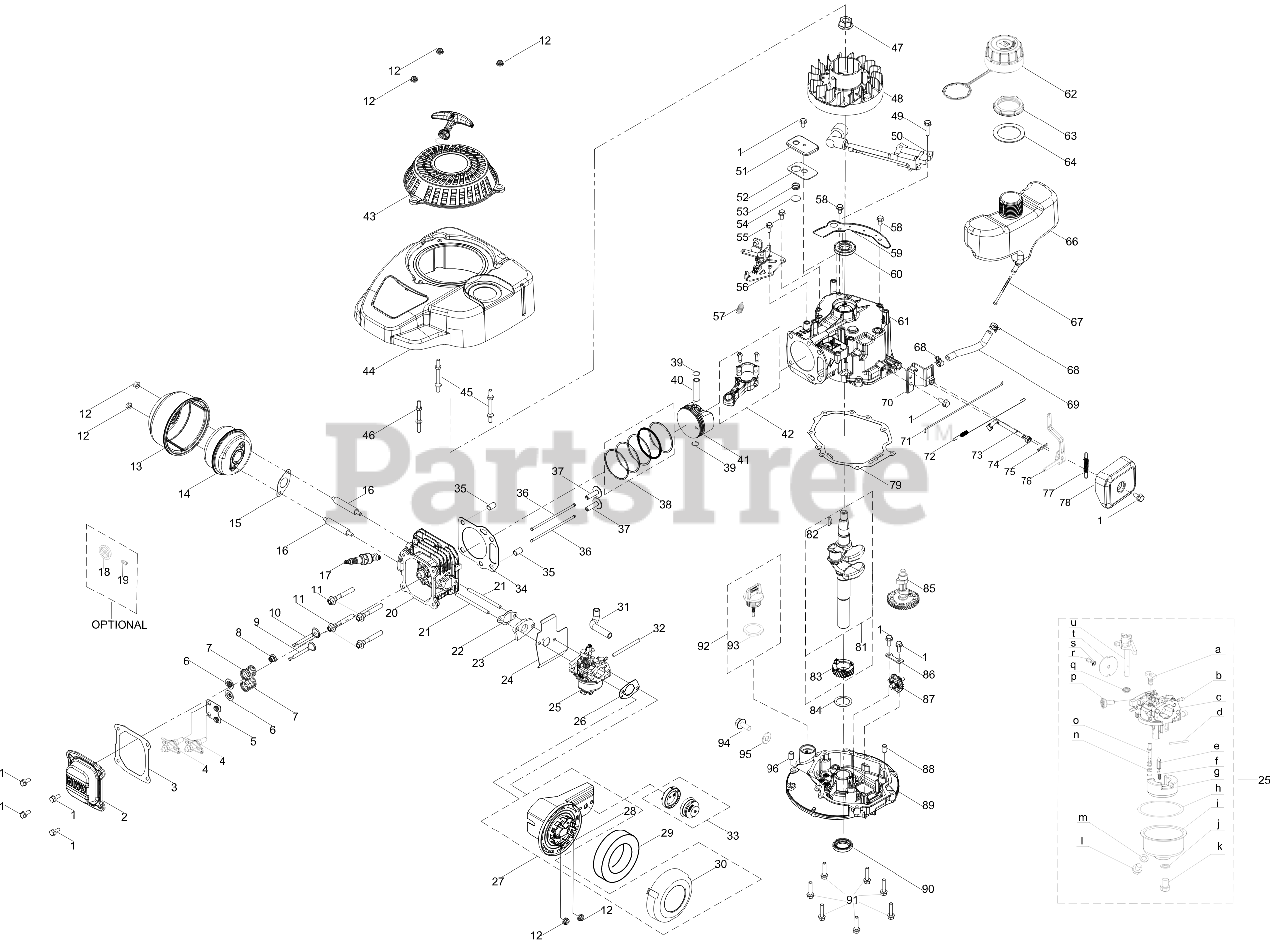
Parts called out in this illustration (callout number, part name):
1	BOLT M6-1 x 14 GR8.8
2	VALVE COVER
3	VALVE COVER GASKET
4	ROCKER ARM ASSEMBLY
5	PUSH ROD GUIDE
6	VALVE SPRING RETAINER
7	VALVE SPRING
8	INTAKE VALVE SEAL
9	EXHAUST VALVE
10	INTAKE VALVE
11	SCREW M8 x 54 GR10
12	HEX NUT
13	MUFFLER SHIELD
14	MUFFLER ASSEMBLY
15	MUFFLER GASKET
16	STUD M6-1 x 76
17	SPARK PLUG
18	SPARK ARRESTOR
19	SCREW M3.5 x 9.5
20	CYLINDER HEAD
21	STUD M6 x 98
22	CARBURETOR INSULATOR GASKET
23	CARBURETOR INSULATOR
24	CARBURETOR GASKET
25	CARBURETOR
26	AIR FILTER BASE GASKET
27	AIR FILTER ASSEMBLY
28	AIR FILTER BASE
29	FOAM AIR FILTER
29	Genuine Factory Parts AIR FILTER
30	AIR FILTER COVER
31	BREATHER HOSE
32	PRIMER HOSE
33	VENTED PRIMER ASSEMBLY
34	CYLINDER HEAD GASKET
35	DOWEL PIN
36	PUSH ROD
37	TAPPET (LIFTER)
38	PISTON RING SET
39	SNAP RING-PISTON PIN
40	PISTON PIN
41	PISTON
42	CONNECTING ROD ASSEMBLY
43	STARTER RECOIL ASSEMBLY
44	ENGINE SHROUD ASSEMBLY
45	STUD M6 x 75
46	STUD M6 x 73
47	FLYWHEEL NUT
48	FLYWHEEL
49	BOLT M6-1 x 25 GR8.8
50	IGNITION COIL ASSEMBLY
51	BREATHER COVER PLATE
52	BREATHER COVER GASKET
53	BREATHER VALVE SPRING
54	BREATHER VALVE
55	BOLT M6-1 x 12 GR8.8
56	ENGINE BRAKE ASSEMBLY
57	BRAKE SPRING
58	BOLT M6-1 x 10 GR8.8
59	SHROUD COVER PLATE
60	UPPER CRANKSHAFT SEAL
61	CRANKCASE
62	FUEL CAP W/TETHER
63	FUEL TANK NUT
64	FUEL TANK UPPER GROMMET
66	FUEL TANK
67	FUEL FILTER
67	Genuine Factory Parts FUEL FILTER
68	HOSE CLAMP
69	FUEL HOSE
70	COMPONENT BRACKET
71	THROTTLE LINKAGE
72	THROTTLE LINKAGE SPRING
73	GOVERNOR ARM SHAFT
74	GOVERNOR SEAL
75	COTTER PIN
76	GOVERNOR ARM ASSEMBLY
77	GOVERNOR SPRING
78	GOVERNOR SHIELD
79	CRANKCASE COVER GASKET
81	CRANKSHAFT
82	FLYWHEEL KEY
83	CRANKSHAFT TIMING GEAR
84	THRUST WASHER
85	CAMSHAFT
86	GOVERNOR GEAR MOUNTING PLATE
87	GOVERNOR GEAR/SHAFT ASSEMBLY
88	DOWEL PIN
89	CRANKCASE COVER
90	LOWER CRANKSHAFT SEAL
91	BOLT-M6-1 x 28 GR8.8
92	DIPSTICK ASSEMBLY
93	DIPSTICK O-RING
94	OIL DRAIN PLUG
95	WASHER
96	DOWEL PIN
